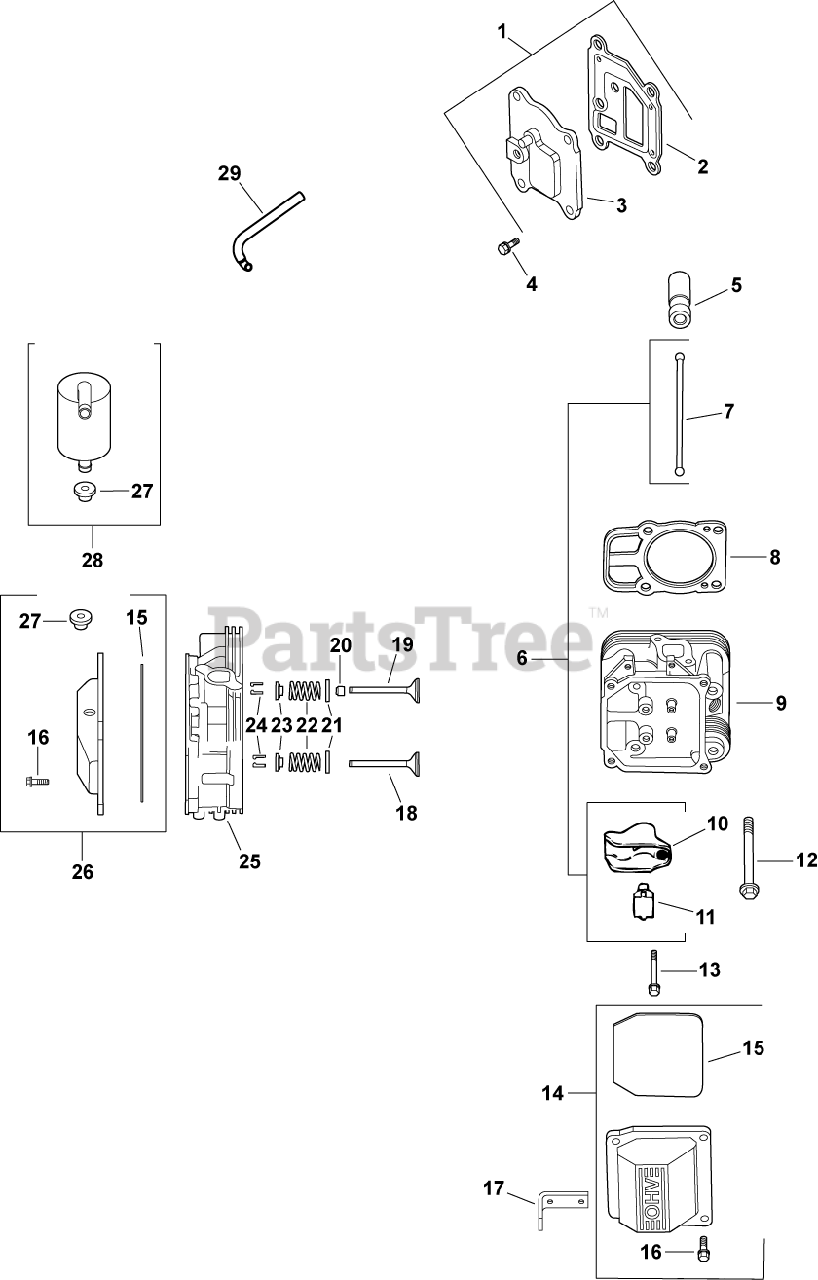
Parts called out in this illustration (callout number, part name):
1	KIT, BREATHER COVER W/GASKET
2	GASKET, BREATHER-USE 24 041 67-S
3	COVER, BREATHER -USE 24 096 125-S
4	SCREW,FLG THD FRM M6X1.0X20-(#25086396S)
5	LIFTER, HYDRAULIC VALVE-USE 25 351 10-S
6	KIT, VALVE TRAIN
7	ROD, PUSH
8	CYL HEAD GASKET KIT-USE 24 841 04-S
9	KIT, CYLINDER HEAD #1
10	ARM, ROCKER
11	PIVOT, CYLINDRICAL ROCKER ARM-USE 24 599
12	SCREW - USE 62 086 08-S
13	SCREW, ROCKER ARM PIVOT-USE M-640034-S
14	KIT, VALVE COVER-PLAIN
15	O-RING (YELLOW) -USE 24 153 30-S
16	SCREW, FLG M6X1.0X30
17	STRAP, LIFTING-USE 25 445 03-S
18	VALVE, EXHAUST (STD) - USE 32 016 01-S
19	VALVE, INTAKE (STD)
20	SEAL, VALVE STEM - (#2503214S)
21	RETAINER, SPRING
22	SPRING, VALVE
23	RETAINER, VALVE SPRING - USE 25 173 28-S
24	KIT, RETAINER
25	KIT, CYLINDER HEAD #2
26	KIT, VALVE COVER
27	GROMMET, RUBBER
28	KIT, BREATHR SEPARATR-(#24755241S)
29	HOSE, BREATHER-USE 24 326 93-S
2401602-S	VALVE, EXHAUST (.25)
2401702-S	VALVE, INTAKE (.25)
